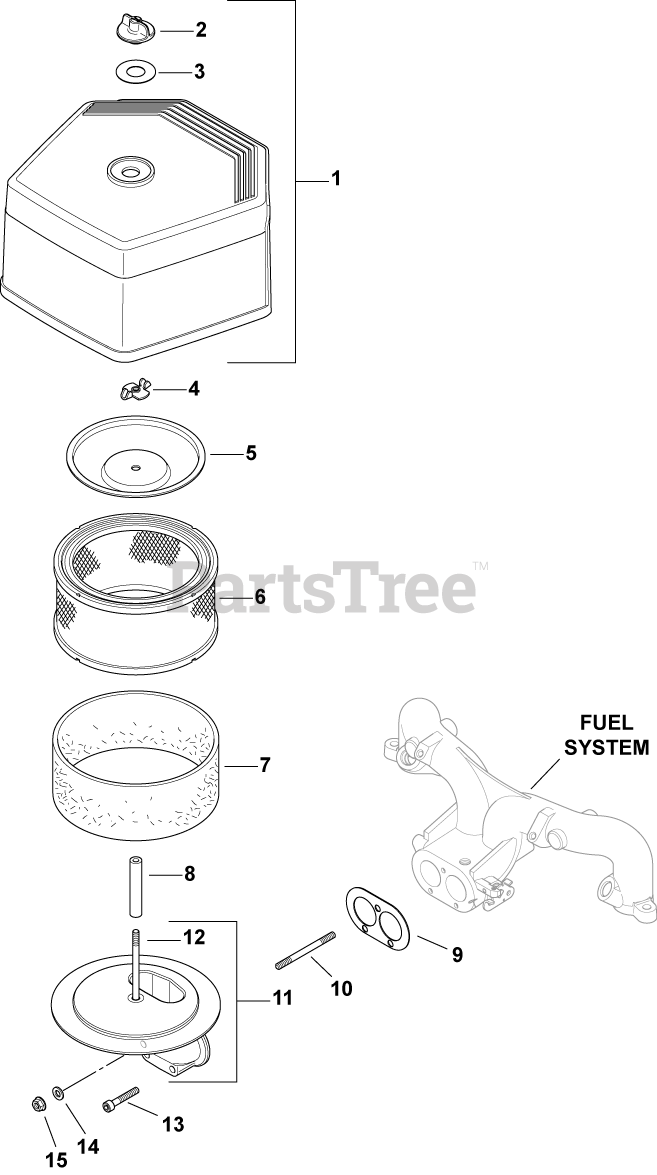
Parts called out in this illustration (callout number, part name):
1	KIT, AIR CLEANER CV (WAWB)
2	KNOB, COVER
3	GASKET, AIR CLEANER COVER KNOB
4	NUT, WING
5	COVER, INNER AIR CLEANER
6	ELEMENT, AIR CLEANER - Also available Retail Packaged 45 883 02-S1 Air Filter Kit
7	ELEMENT, PRE-CLEANER
9	GASKET, AIR CLEANER BASE
10	STUD, M6X1.0X75 - DISCONTINUED
11	ELBOW ASSEMBLY, AIR CLEANER
12	STUD, M6X1.0X93MM
13	SCREW, SKT CAP M6X1.0X35
15	NUT, FLG M6X1.0
